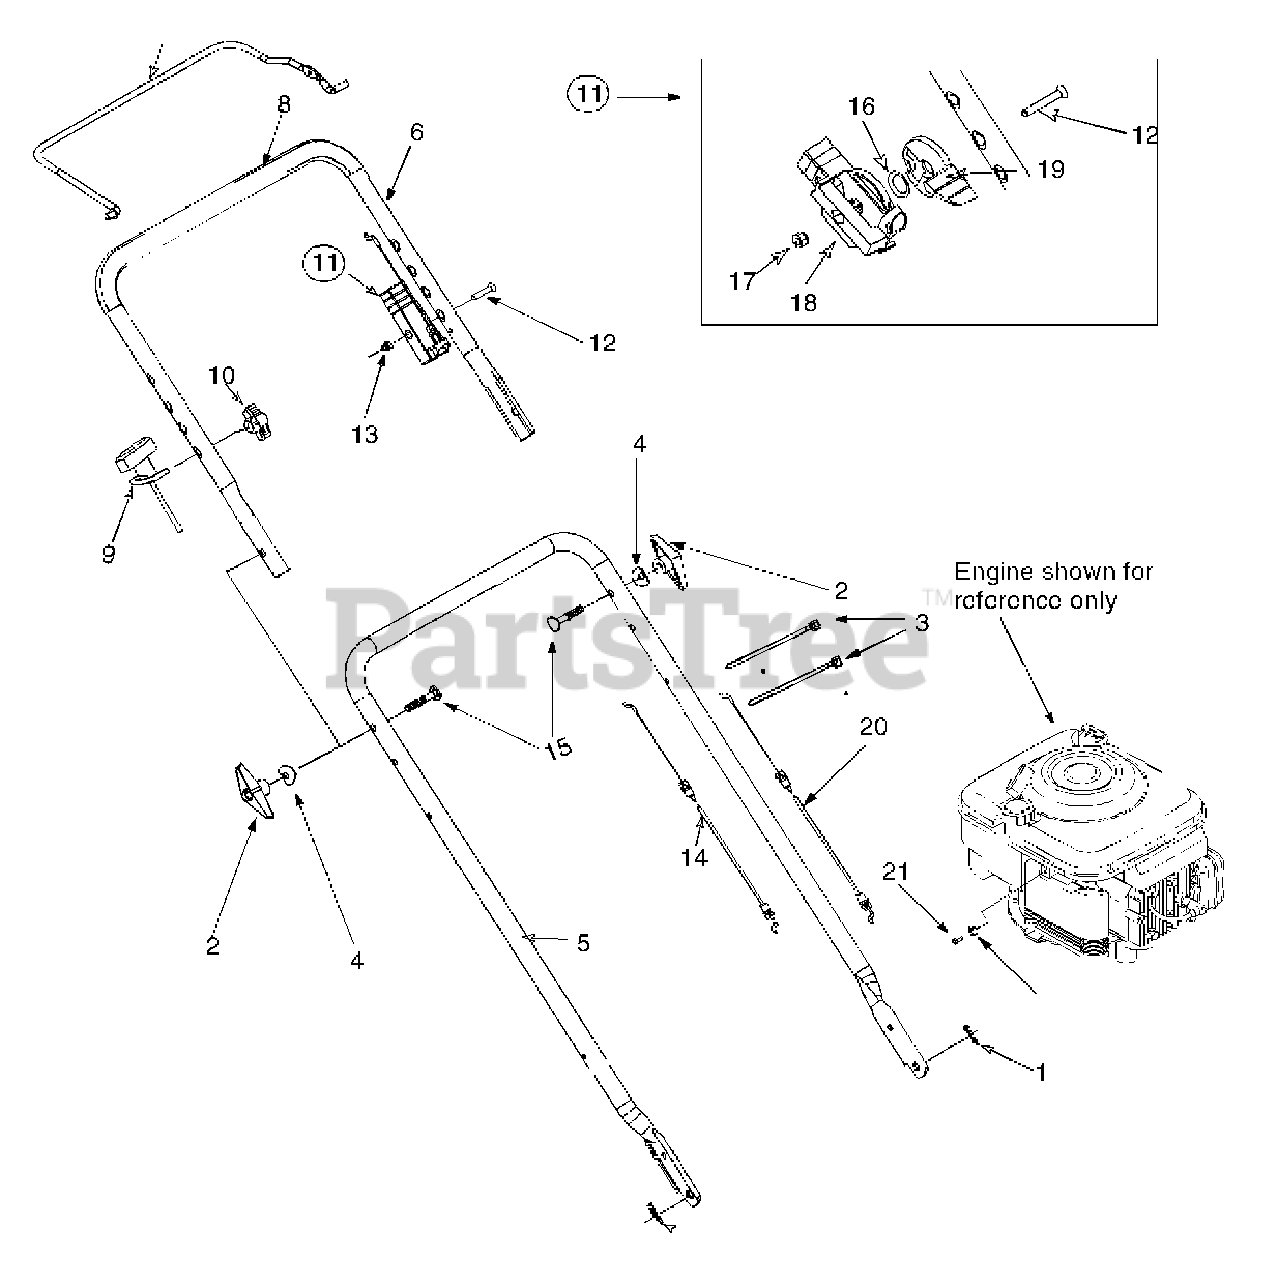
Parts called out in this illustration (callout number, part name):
1	Hairpin Clip
2	Wing Nut
3	Cable Tie
4	Saddle Washer
11	Throttle Control Assembly
12	Oval C-Sunk Scr.
13	Hex L-Nut 1/4-20 Thd.
14	Control Cable
15	Carriage Bolt
16	Spring Washer
17	Hex Lock Nut 1/4-20
18	Throttle Housing
19	Throttle Lever
20	Throttle Cable
21	Hex Screw
